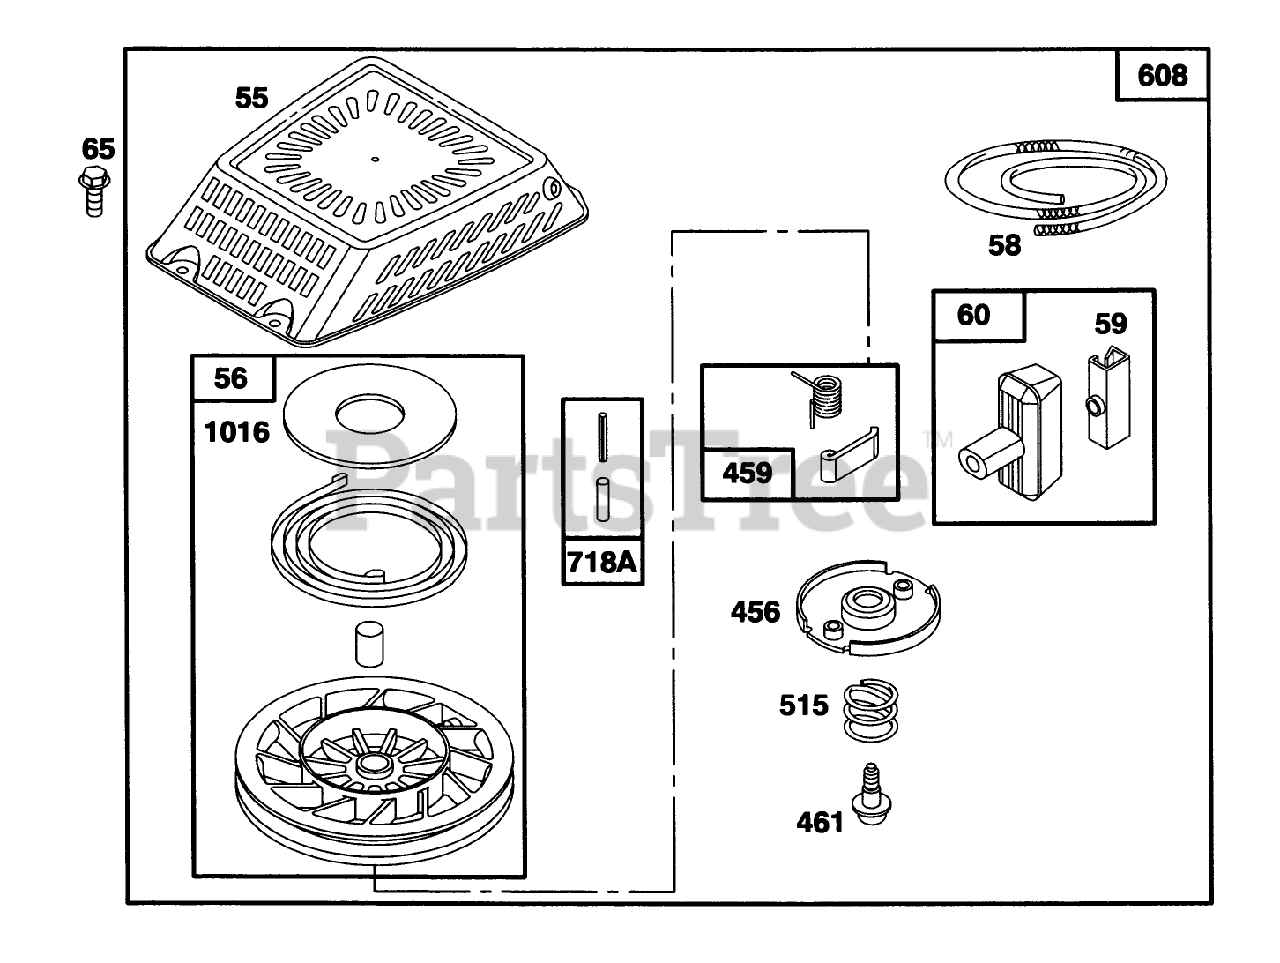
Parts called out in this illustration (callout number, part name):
59	INSERT-HANDLE, REWIND
456	RETAINER - SPRING
515	SPRING - RETAINER
